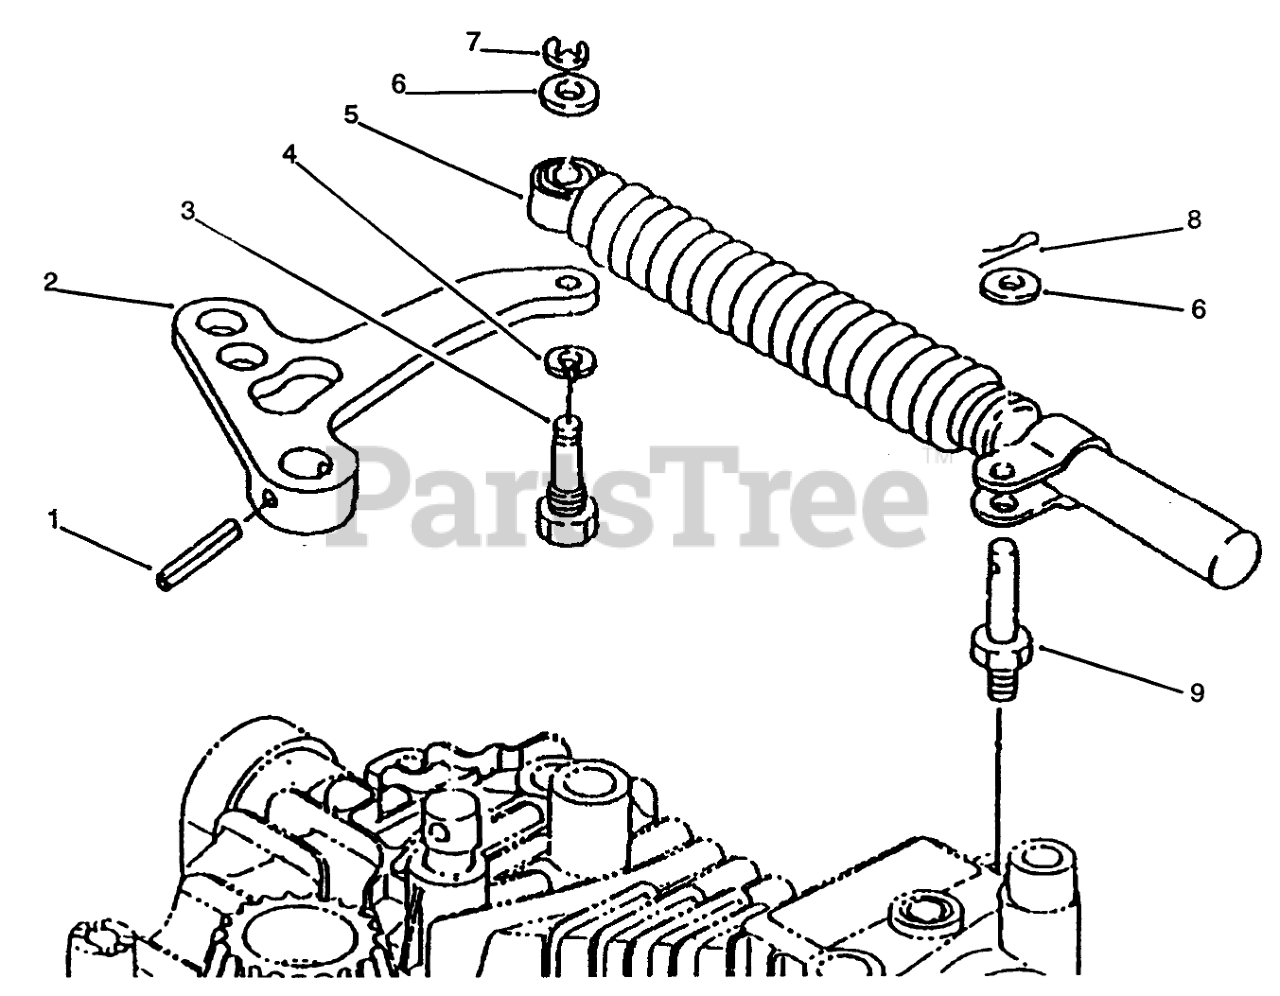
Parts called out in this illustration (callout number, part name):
1	Pin-Roll (Only On: 72083, 72043, 72103, 72063)
2	Arm (Only On: 72083, 72043, 72103, 72063)
3	Bolt (Only On: 72083, 72043, 72103, 72063)
4	Washer (Only On: 72083, 72043, 72103, 72063)
5	Shock Absorber (Only On: 72083, 72043, 72103, 72063)
6	Washer (Only On: 72083, 72043, 72103, 72063)
7	Ring (Only On: 72083, 72043, 72103, 72063)
8	Pin-Cotter (Only On: 72083, 72043, 72103, 72063)
9	Stud (Only On: 72083, 72043, 72103, 72063)
